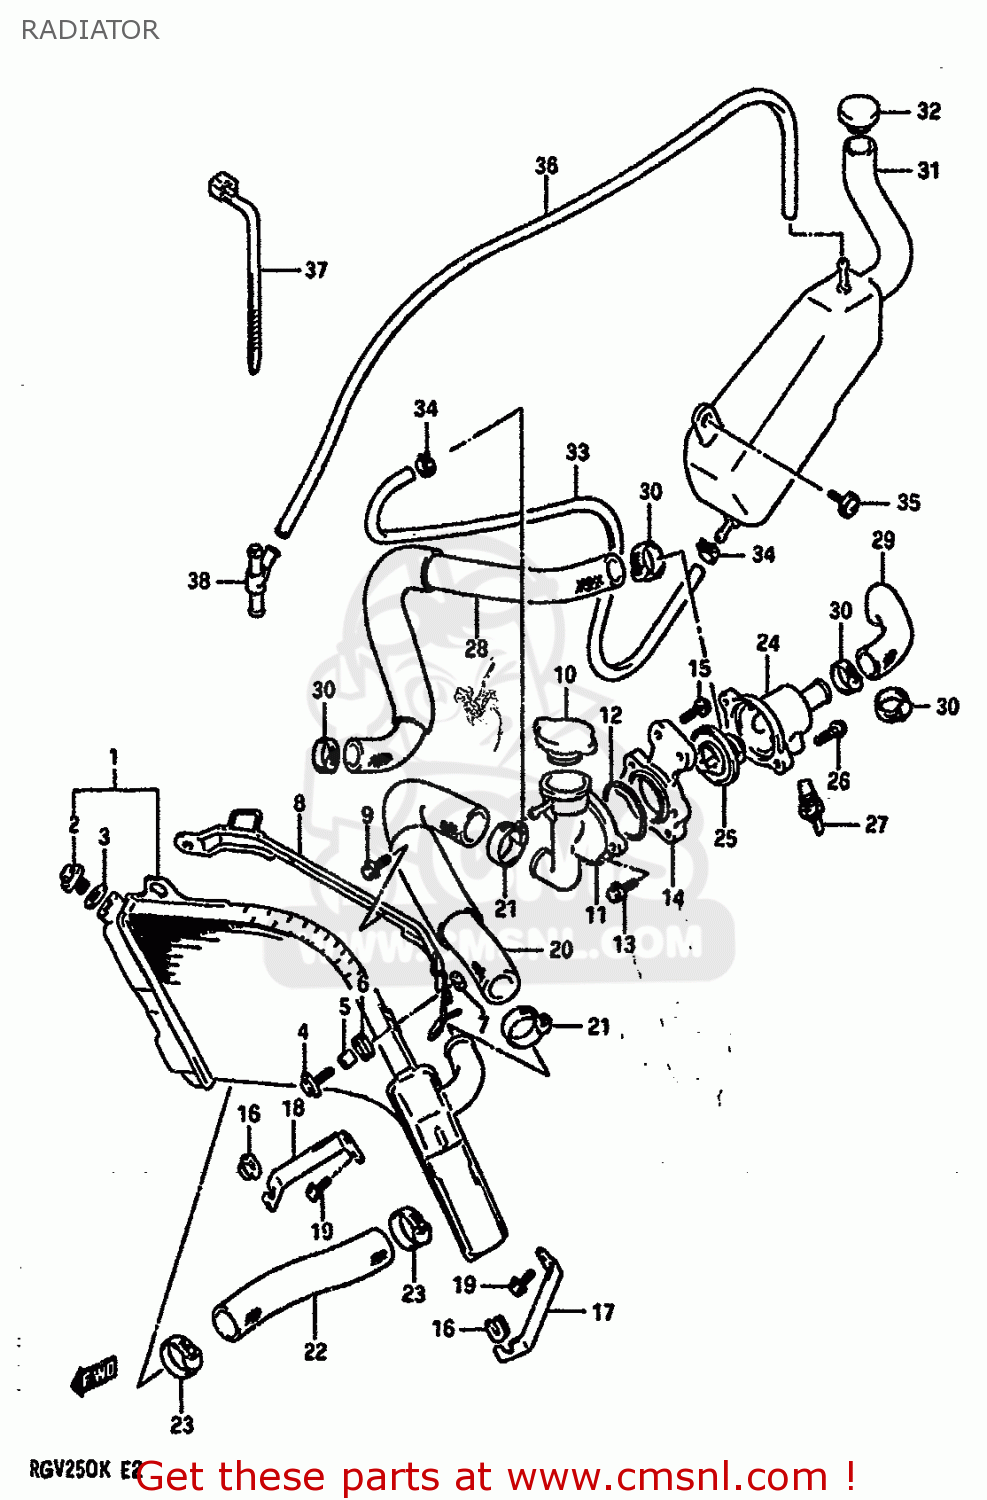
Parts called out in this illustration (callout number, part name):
1	RADIATOR ASSY,WATER
2	PLUG
3	GASKET
4	BOLT 6X20
5	SPACER (6.8X10X10)
6	CUSHION
7	NUT 6MM
8	BRACKET,RADIATOR UPPER
9	BOLT
10	CAP,RADIATOR 1.1
11	CONDUCTION,RADIATOR
12	O RING(D:2.4,ID:43.2)
13	BOLT 6X16
14	BRACKET,CONDUCTION
15	BOLT
16	CUSHION,OIL COOLER NO.2
17	BRACKET,RADIATOR LOWER LH
18	BRACKET,RADIATOR LOWER RH
19	BOLT
20	HOSE,RADIATOR INLET
21	CLAMP
22	HOSE,RADIATOR OUTLET
23	CLAMP
24	CONNECTOR,THERMOSTAT INLET
25	THERMOSTAT,WATER
26	BOLT 6X20
27	GAUGE ASSY,WATER TEMPERATURE
28	HOSE,RADIATOR JOINT NO.1
29	HOSE,RADIATOR JOINT NO.2
30	CLAMP
31	TANK ASSY,RESERVOIR
32	CAP,RESERVOIR TANK
33	HOSE,RESERVOIR TANK INLET
34	CLIP
35	SCREW(6X16)
36	HOSE
37	CLAMP
38	3 WAY
